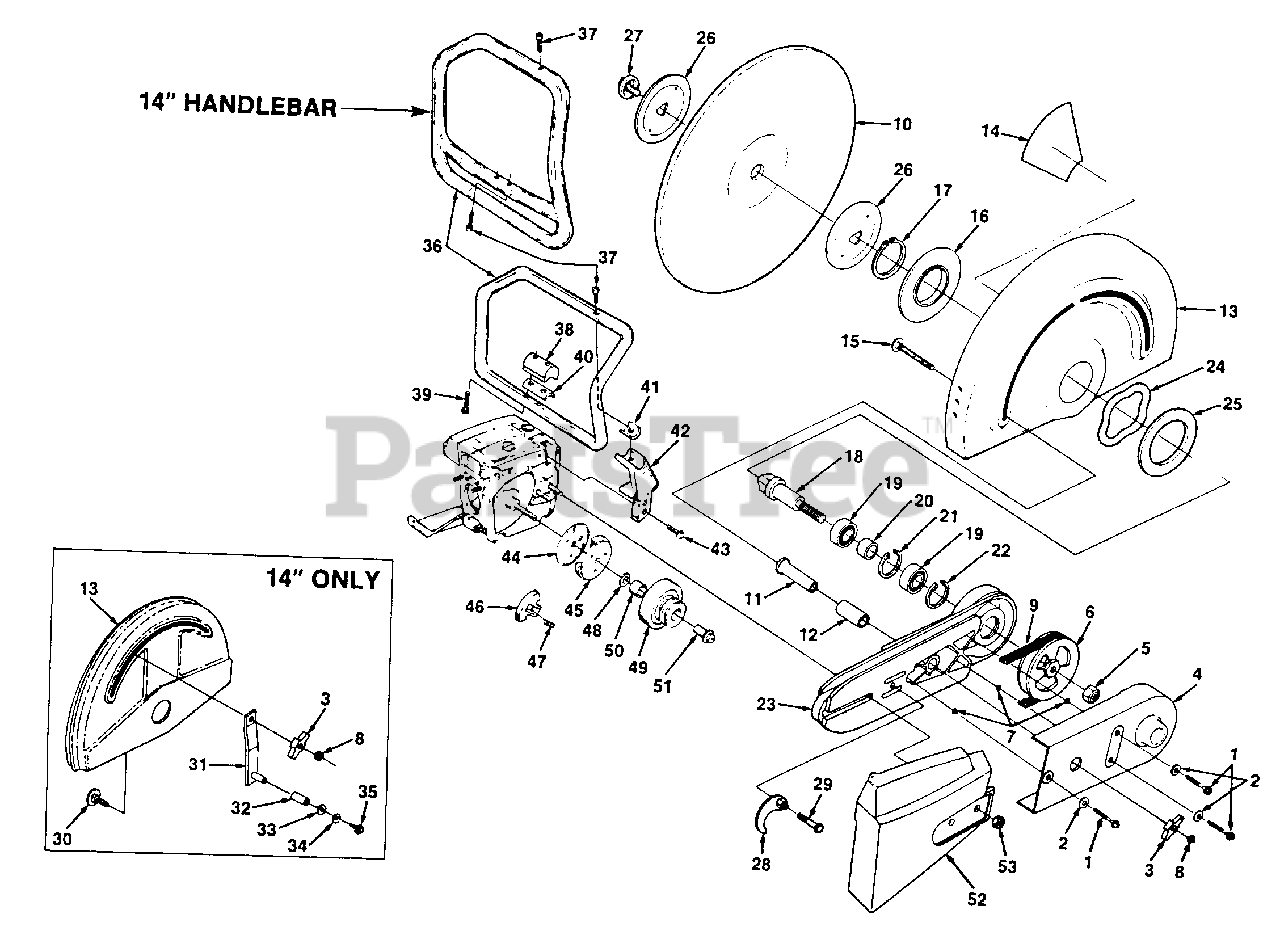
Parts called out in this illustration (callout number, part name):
1	SCREW-Slotted (1/4-20 x 1 1/2)
2	WASHER-Flat 1/4
3	KNOB-Handle
4	COVER-Arm
5	NUT-Lock hex 1/2-13
6	PULLEY-Driven
7	"O" RING
8	NUT-Hex 5/16-18
9	BELT-"V" Drive
10	WHEEL-Resinoid
11	SPACER-Guard adjusting
12	TUBING-Rubber
13	GUARD-Wheel
14	LABEL-Caution
15	BOLT-Step 5/16-18 x 3 1/2
16	WASHER-Mounting
18	SHAFT-Wheel
19	BEARING-Ball
20	SPACER-Bearing
21	RING-Retaining
22	RING-Retaining
23	ARM-Wheel
24	SPRING-Wave
26	FLANGE-Wheel
27	KIT-Screw, Washer & Retaining
28	CAM & ADJUSTER
29	SCREW-Hex hd. 5/16-18 x 1 1/2
30	BOLT-Step
31	ARM-Adjusting
32	TUBING-Rubber
33	WASHER-Flat 5/16
34	WASHER-Lock 1/4
35	SCREW-Hex cap 114-20 x 5/8
36	HANDLE BAR
37	SCREW-Nylock 1/4-20 x 1"
39	SCREW-Nylock 1/4-20 x 1 7/8
40	MOUNT-Shock (spacer)
41	MOUNT-Shock (bracket)
42	BRACKET-Handle Bar
43	SCREW-Hex hd. 12-24 x 3/4
44	COVER-Clutch
45	PLATE-Clutch back
46	SHOE-Clutch
47	SPRING-Clutch
49	PULLEY-Bearing & Arm
50	BEARING
51	RACE-Inner bearing
52	COVER-Drivecase
53	NUT-3/8-16
